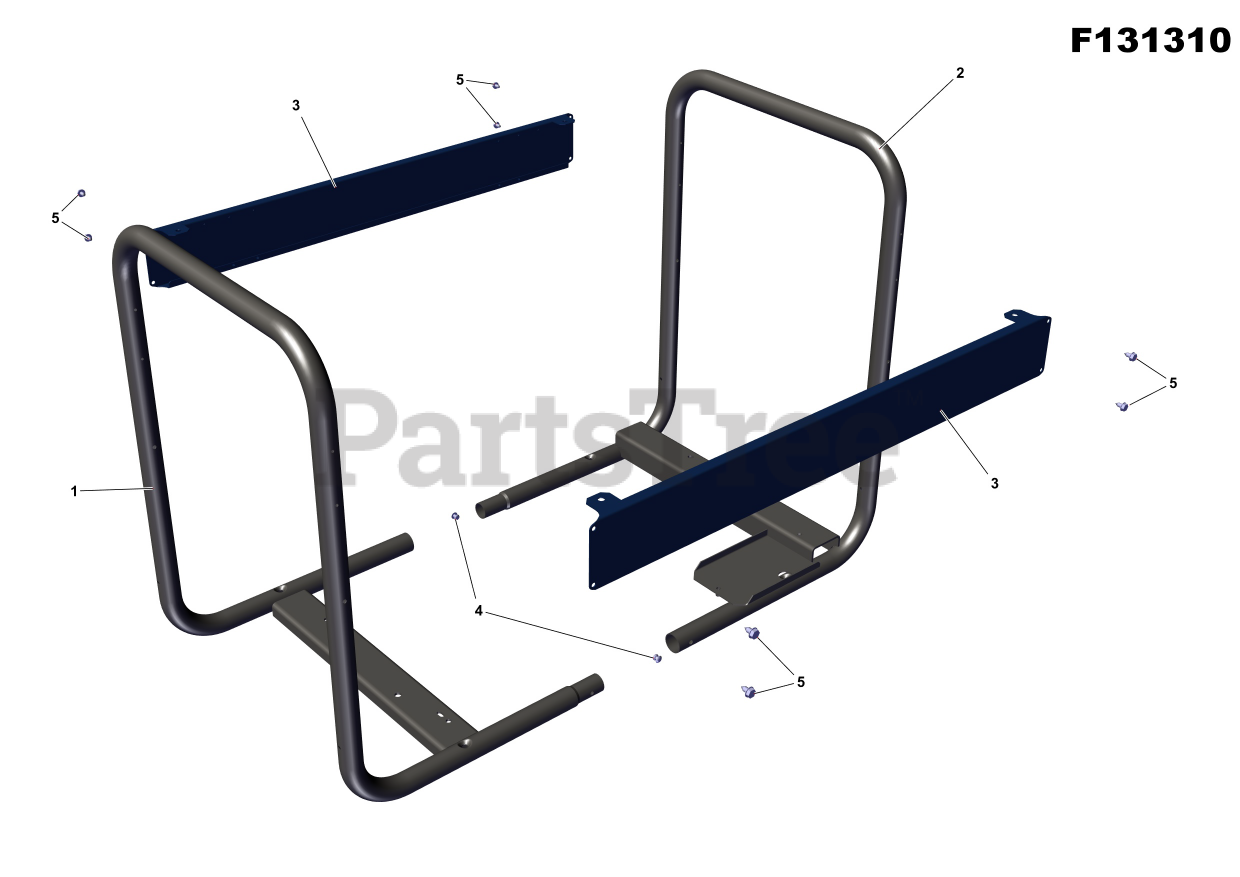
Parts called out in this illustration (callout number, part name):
1	Half frame engine
2	Alternator frame
3	Lateral band
